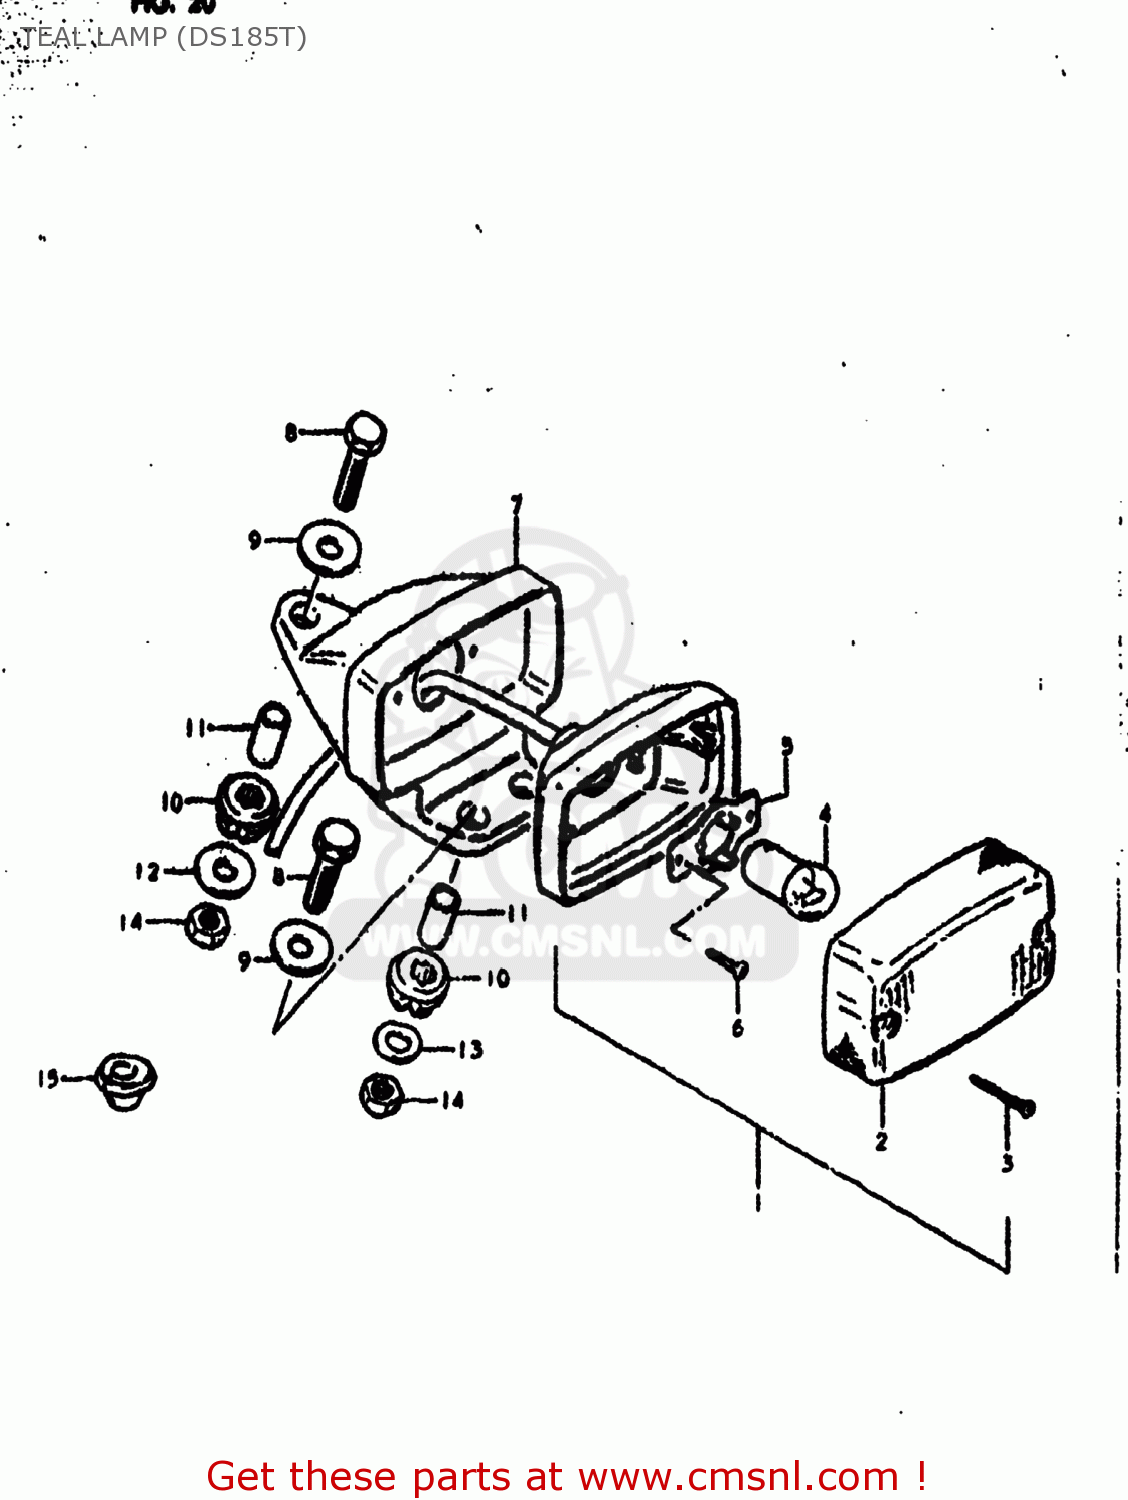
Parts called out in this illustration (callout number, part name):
1	LAMP UNIT,TAIL
2	LENS
3	SCREW
4	BULB(6V5W,TOKAI DENSO)
5	PLATE,TURN SIGNAL
6	SCREW,REAR COMBINATION LAMP LENS
7	BRACKET,REAR COMBINATION LAMP
8	BOLT
9	WASHER (6.5X20X1.2)
10	CUSHION
11	SPACER
12	WASHER (6.5X20X1.2)
13	WASHER
14	NUT
15	GROMMET
